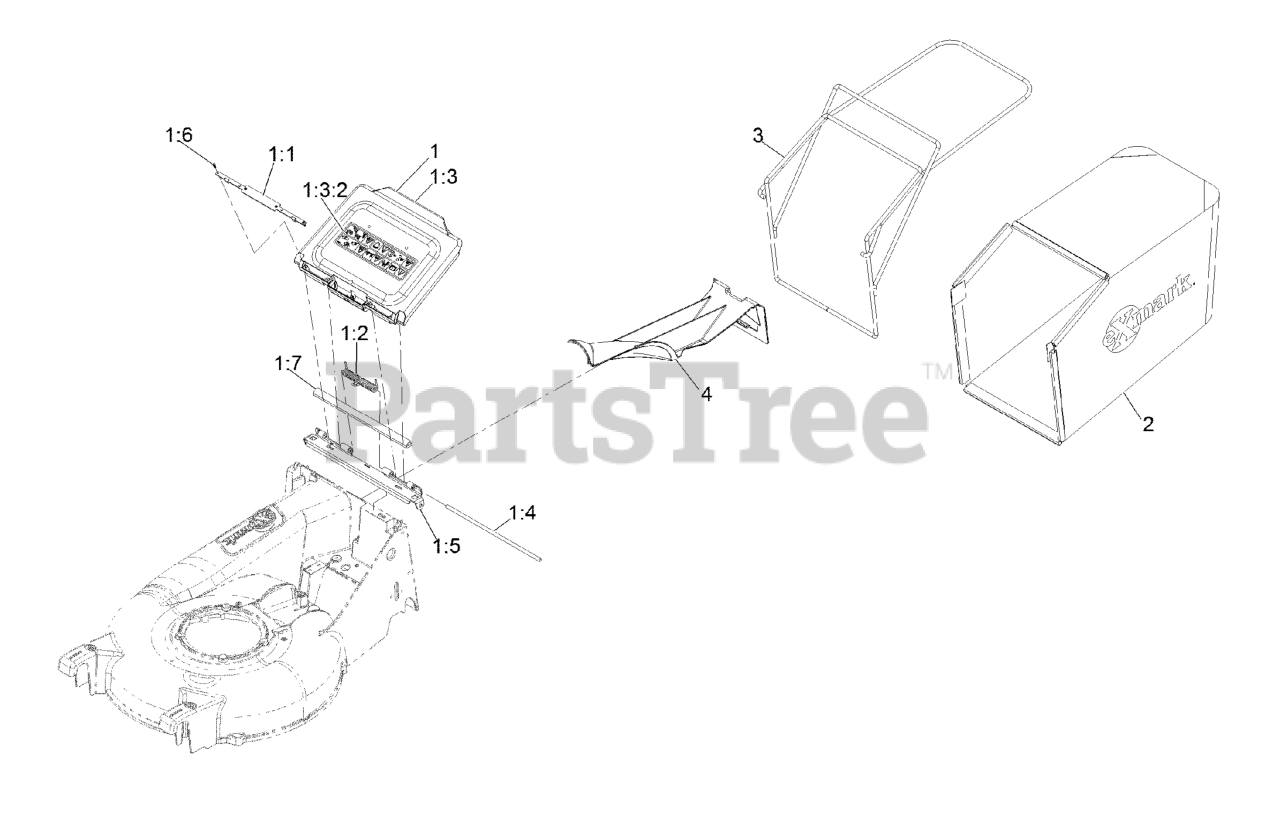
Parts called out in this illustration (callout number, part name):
1	DOOR ASM
1:1	PLATE, DOOR COVER
1:2	SPRING-PLASTIC DOOR
1:3	ASM-DOOR & DECAL
1:3:2	DECAL-WARNING
1:4	PIN-DOOR PIVOT
1:5	BRACKET-DOOR PIVOT
1:6	SCR,TAP,6-19X7/16,PHPH, S
1:7	SEAL-EPDM FOAM BULB
2	BAG-21 GRASS
3	WLD-BAG FRAME
4	PLUG,MULCH
